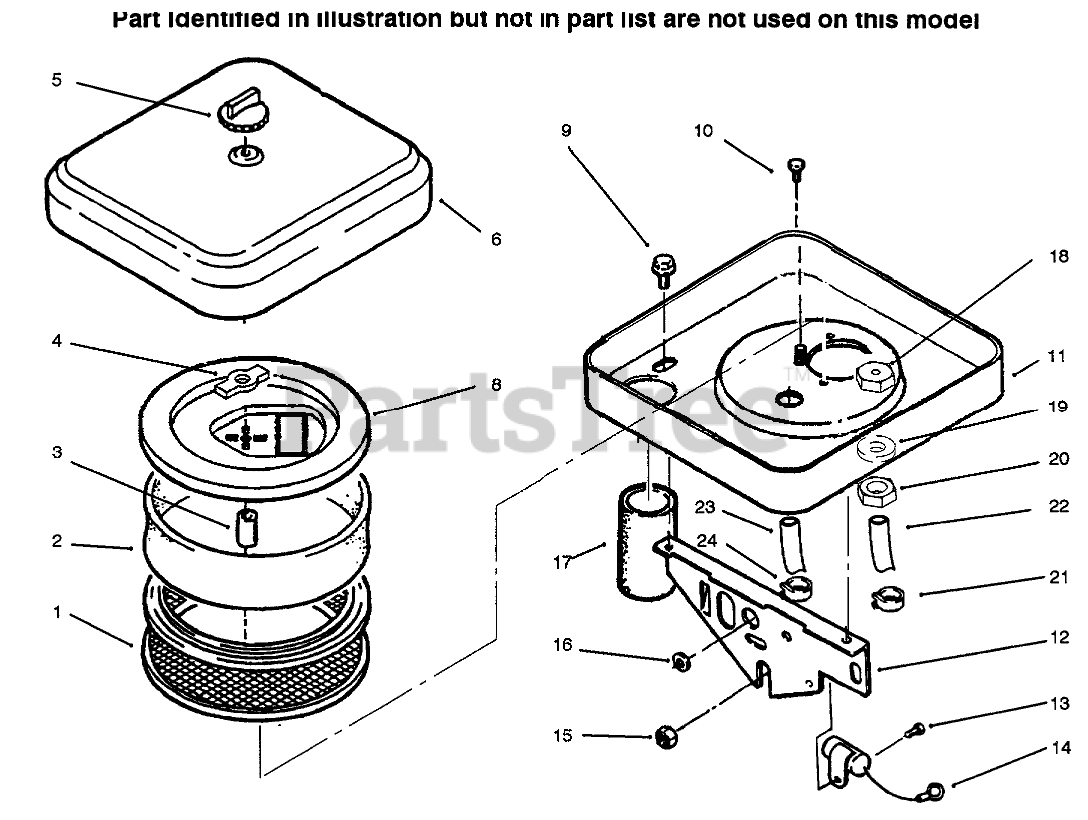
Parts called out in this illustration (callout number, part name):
1	AIR-CLEANER ELEMENT
2	AIR CLEANER ELEMENT
3	SPACER-1" LG
4	SPACER-RUBBER
6	COVER - AIR CLEANER
8	ELEMENT COVER KIT
9	SCREW-TAPPING
10	MACHINE SCREW
11	AIR-CLEANER HOUSING
12	SUPPORT-AIR CLEANER
13	SCREW #10-32 X 5/8
14	CONDENSER
16	GROMMET
17	AIR INTAKE TUBE
19	HOSE FITTING GASKET
